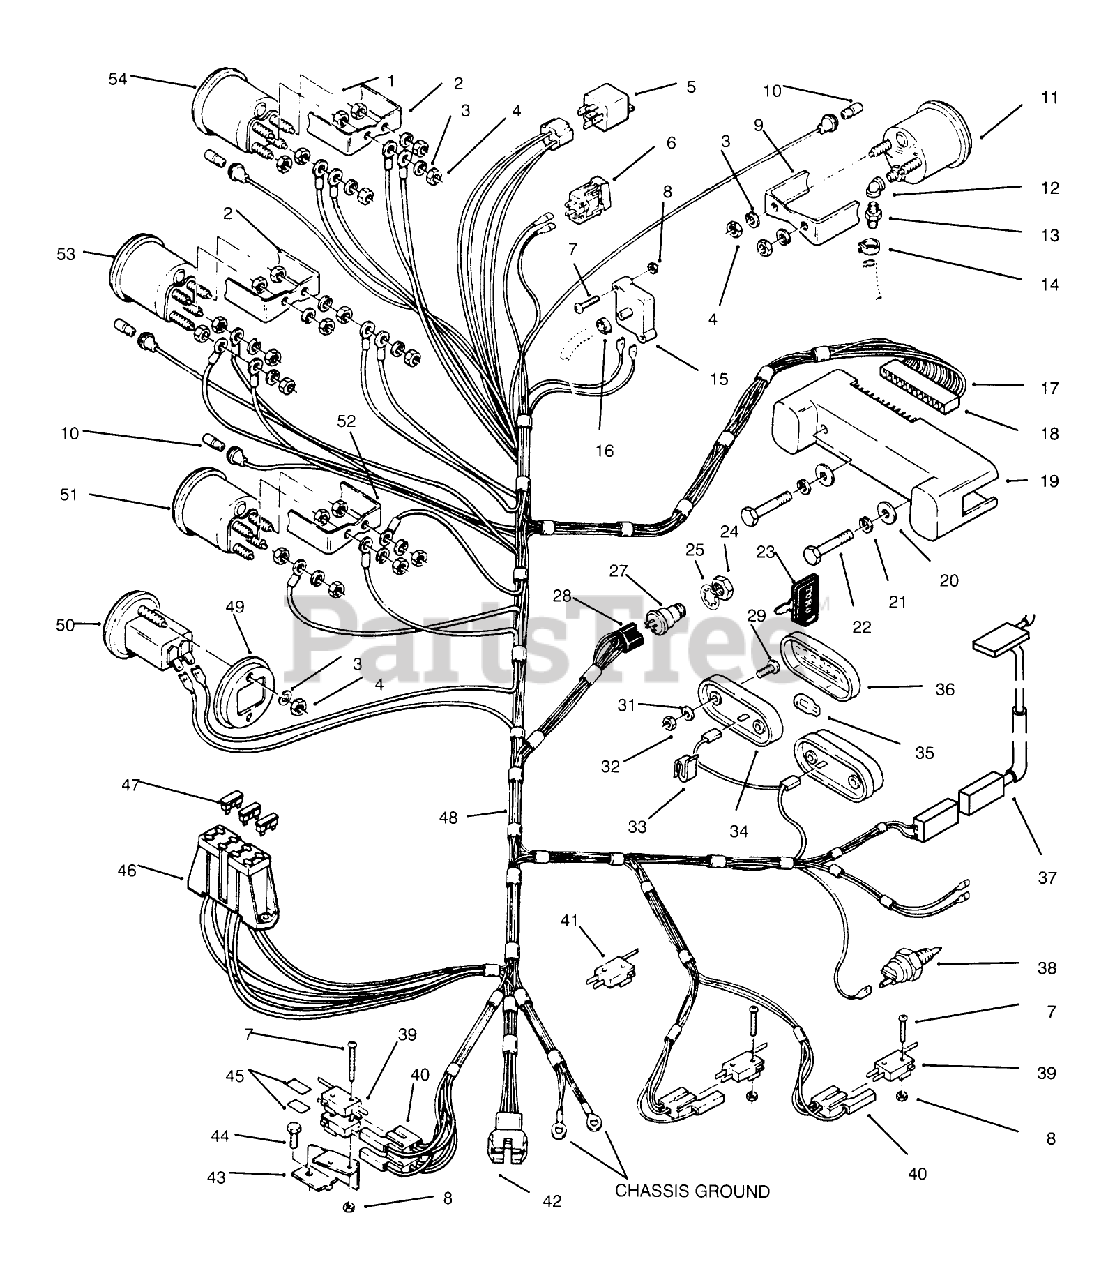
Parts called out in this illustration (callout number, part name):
2	CLAMP-MOUNTING
4	NUT-HEX
5	RELAY
9	Bracket-Mounting
12	ELBOW
17	Terminal
18	Connector-Male
20	WASHER-FLAT
21	WASHER-LOCK
22	SCREW
23	KEY-IGNITION
25	WASHER-LOCK
29	SCREW-PPH
31	WASHER-LOCK, INT
32	NUT-LOCK, NI
35	LIGHT BULB
36	LENS-TAIL LIGHT
37	SWITCH-SEAT
39	SWITCH
40	CONNECTOR BODY
41	SWITCH - CLUTCH
42	9-CIRCUIT CAP
44	Bolt
45	BARRIER - SWITCH
49	CLAMP-HOUR METER
51	TACHOMETER
52	BRACKET - GAUGE MOUNT
